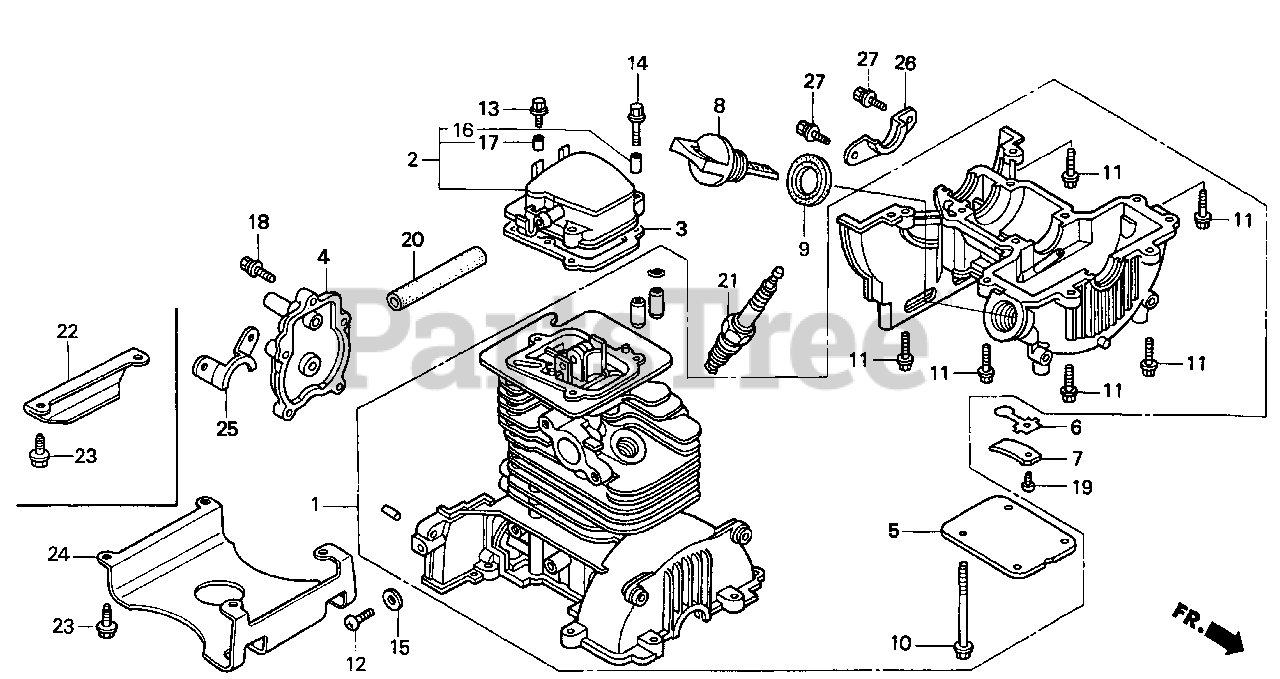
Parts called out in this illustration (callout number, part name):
1	CRANKCASE SET
2	COVER COMP., HEAD
3	GASKET, HEAD COVER
4	COVER, CAMSHAFT
5	COVER, OIL OUTLET VALVE
6	VALVE, OIL OUTLET
7	PLATE, STOPPER
8	CAP, OIL FILLER
9	GASKET, OIL FILLER CAP
10	BOLT, FLANGE (5X55)
11	BOLT, FLANGE (5X18)
12	SCREW, PAN (6X8)
13	BOLT, FLANGE (5X14)
13	BOLT, FLANGE (5X12)
14	BOLT, FLANGE (5X22)
15	WASHER, SEALING (6.5MM)
16	COLLAR, HEAD COVER
17	COLLAR, TOP COVER
17	COLLAR A, HEAD COVER
18	BOLT-WASHER (4X16)
19	SCREW, PAN (3X5)
20	BULK HOSE, VACUUM (7X3000) (7X68)
21	SPARK PLUG (U16FSR-UB)
21	SPARK PLUG (R5HSB)
25	GUARD A, GRASS
26	GUARD B, GRASS
27	BOLT-WASHER (4X10)
